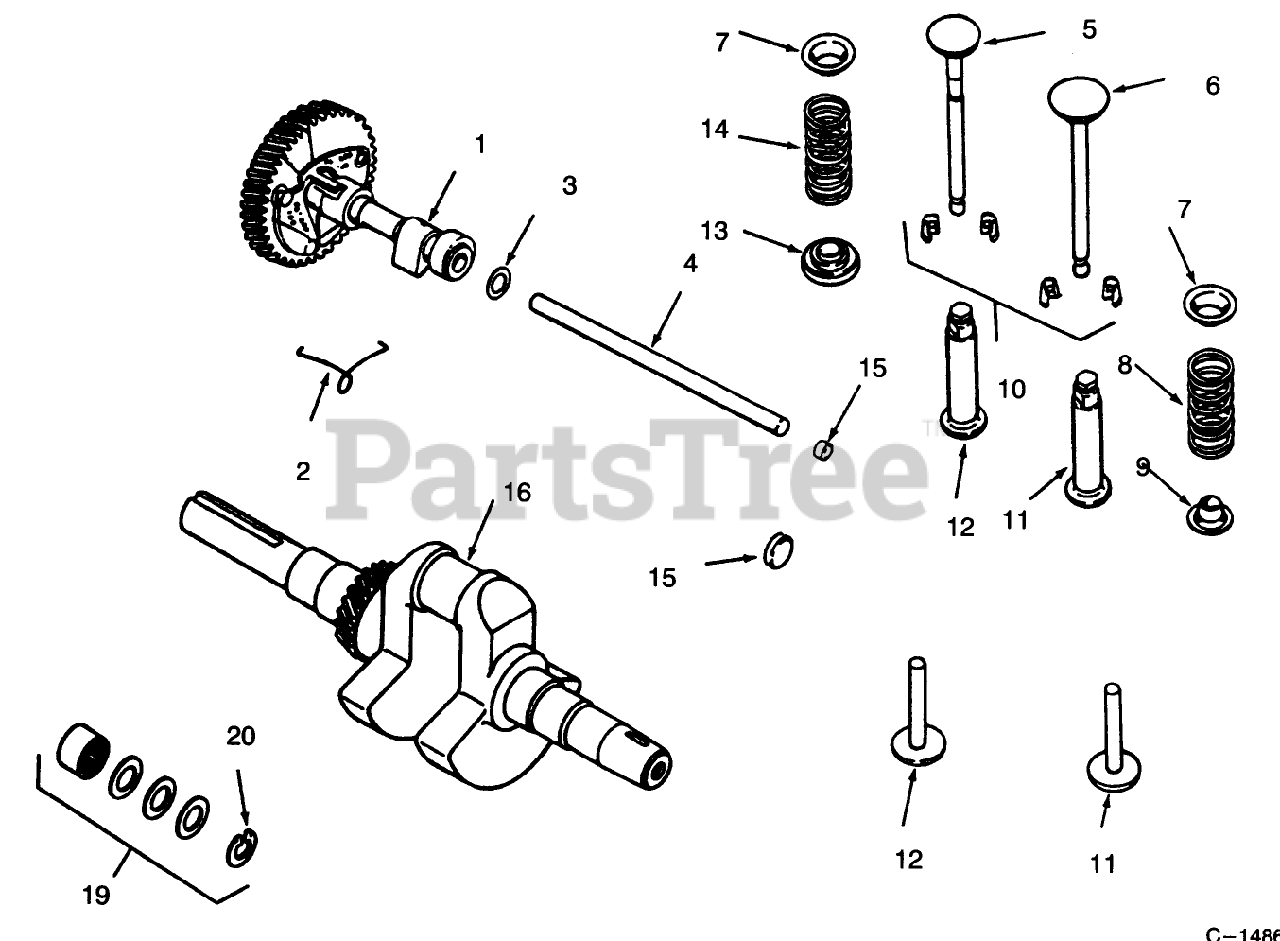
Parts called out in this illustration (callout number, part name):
1	KOHLER 47-010-11
2	KOHLER 47-089-01
3	KOHLER 275066
4	KOHLER 47-380-09
5	KOHLER 235838
6	KOHLER 235008
7	KOHLER 235011
8	KOHLER 235010
9	KOHLER 230011
10	KOHLER 41-755-10
11	KOHLER D-235327
12	KOHLER D-235327
13	KOHLER 52-413-01
14	KOHLER 235168
15	KOHLER X-702-3
16	KOHLER 47-142-02
19	KOHLER 47-755-01
20	KOHLER X-269-34
